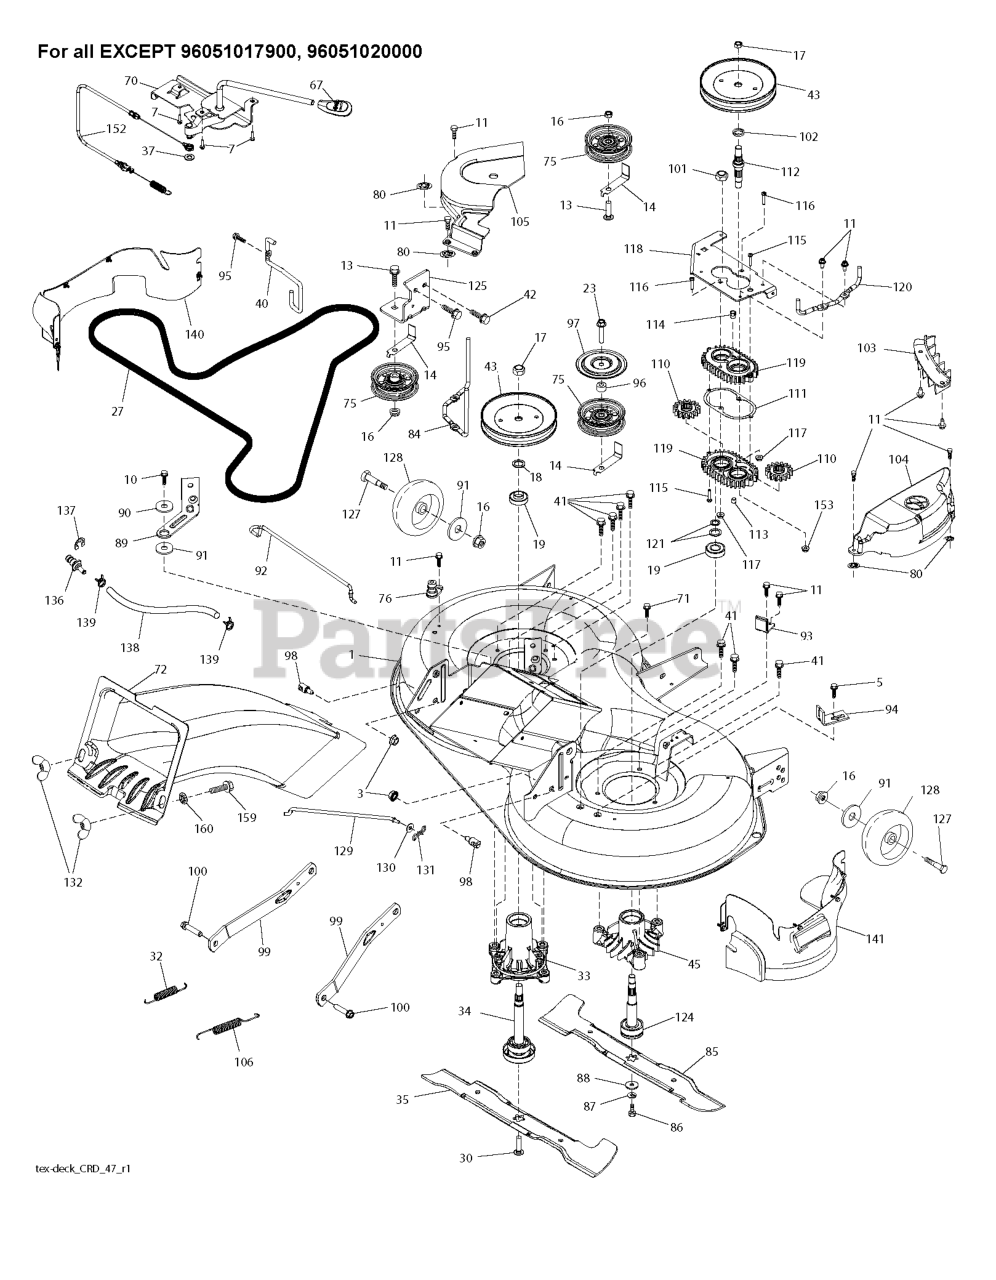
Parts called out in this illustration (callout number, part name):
1	DECK.WELDMENT.97.TEX.498
3	NUT LOCK HEX FLANGE 5/16-18
5	BOLT.5/16HEX.WHS.HD
7	SCREW.#10 X 0.750.BOS
10	SCREW 3/8-16X1
11	SCREW.1/4-20X5/8
13	BOLT.3/8-16X1.50
14	KEEPER, BELT IDLER
16	NUT LOCK FLG 3/8-16 UNC
17	NUT.FLANGE.LOCK.TOP
18	WASHER.SPACER.MANDREL
19	BEARING
19	BEARING.MANDREL.TOP.EXTENDED
23	SCREW LT
27	BELT V-BELT DRIVE
30	BOLT.WASHER.ASM.7/16-2
30	SCREW.SEMS.7/16-20X1.HEX.HEAD
32	SPRING RETURN
33	RP.HOUSING.MANDREL.4PT.
34	SHAFT.ASM.MDRL.N/GREASE.38
34	SHAFT ASM.MNDRL.N/GREASEABLE
35	BLADE.3N1.LH.CRD.97
37	WASHER
40	KEEPER BELT ENGINE LH
41	BOLT.HEX.WASHR.HED.313-18X1.19
42	SCREW
43	PULLEY.MANDREL.5.438.PD
45	HOUSING.MANDREL.44/46" VENT
67	HANDLE.CLUTCH.CABLE.LT
70	CLUTCH.ASM.MANUAL.LT.PRED
71	SCREW 3/8-16X1/2
72	CHUTE.TEX.CRD.GEN I.97 UPPER
75	FLAT IDLER PULLEY
76	1/2" BARB.DECK.WASHOUT.PORT
80	PALNUT 1/4
84	KEEPER.BELT.MANDREL.PULLEY
85	BLADE.3N1.RH.CRD.97
86	BOLT.3/8-24X1.25GR8. LHTHRD
87	SLW 3/8 STD
88	WASHER.BLADE
89	ARM.BRAKE.97.LH
90	SPACER.RETAINER
91	WASHER
92	ROD ROD BRAKE
93	ARM.BRAKE.97.RH
94	BRKT.CLUTCH.CABLE
95	SCREW, 3/8-16X3/4
96	SPACER
97	PROTECTOR
98	STUD.FASTNER.W/ANTI-ROTATE
99	ARM.SUSPENSION.MOWER.R
100	BOLT.SHOULDER
101	NUT.CROWNLOCK.9/16 -18.UNC
102	SPACER BEARING
103	GUARD GUARD FRONT VENT
104	97.CRD.RH.MANDREL.COVER
105	MANDREL MANDREL COVER LH
106	SPRING.BRAKE.RETURN.38"
110	CRD.SPUR.GEAR
111	GASKET GASKET GEARCASE
112	SHAFT SHAFT. CRD GEARCASE ADAP
113	PLUG PLUG OIL
114	VENT.BREATHER.1/8 NPT
115	SCREW
116	BOLT.CARIGE.SS.1/4-20X1.75GR5
117	NUT T
118	ARM ARM CLUTCHING
119	GEARCASE GEARCASE SUBASM
120	BRACKET KEEPER BELT RH
121	WASHER WASHER
124	MANDREL SHAFT NON/GREASE
125	BRACKET
127	BOLT.SHOULDER.3/8-16X3-5/8.
128	WHEEL.GAUGE.RALLY
129	ROD.ANTI.SWAY.48/54"K4
130	WASHER
131	PIN.COTTER.5/16.BOW TI
132	KNOB.HANDLE.3/8.TRI-POINT.BLAC
136	PLUG WASHOUT PORT HOOKUP
138	HOSE.3/8ID.BULK.12"
139	HOSE.3/8.CLAMP (2 2)
140	GUARD.ASSEMBLY.97.LH.FRENCH
141	GUARD.ASSEMBLY.97.RH.FRENCH
152	CABLE CABLE CLUTCH MANUAL W/S
153	NUT HEXAGON 9/16-18 G2 ZPB LOC
153	NUT.CROWNLOCK.9/16 -18.UNC
